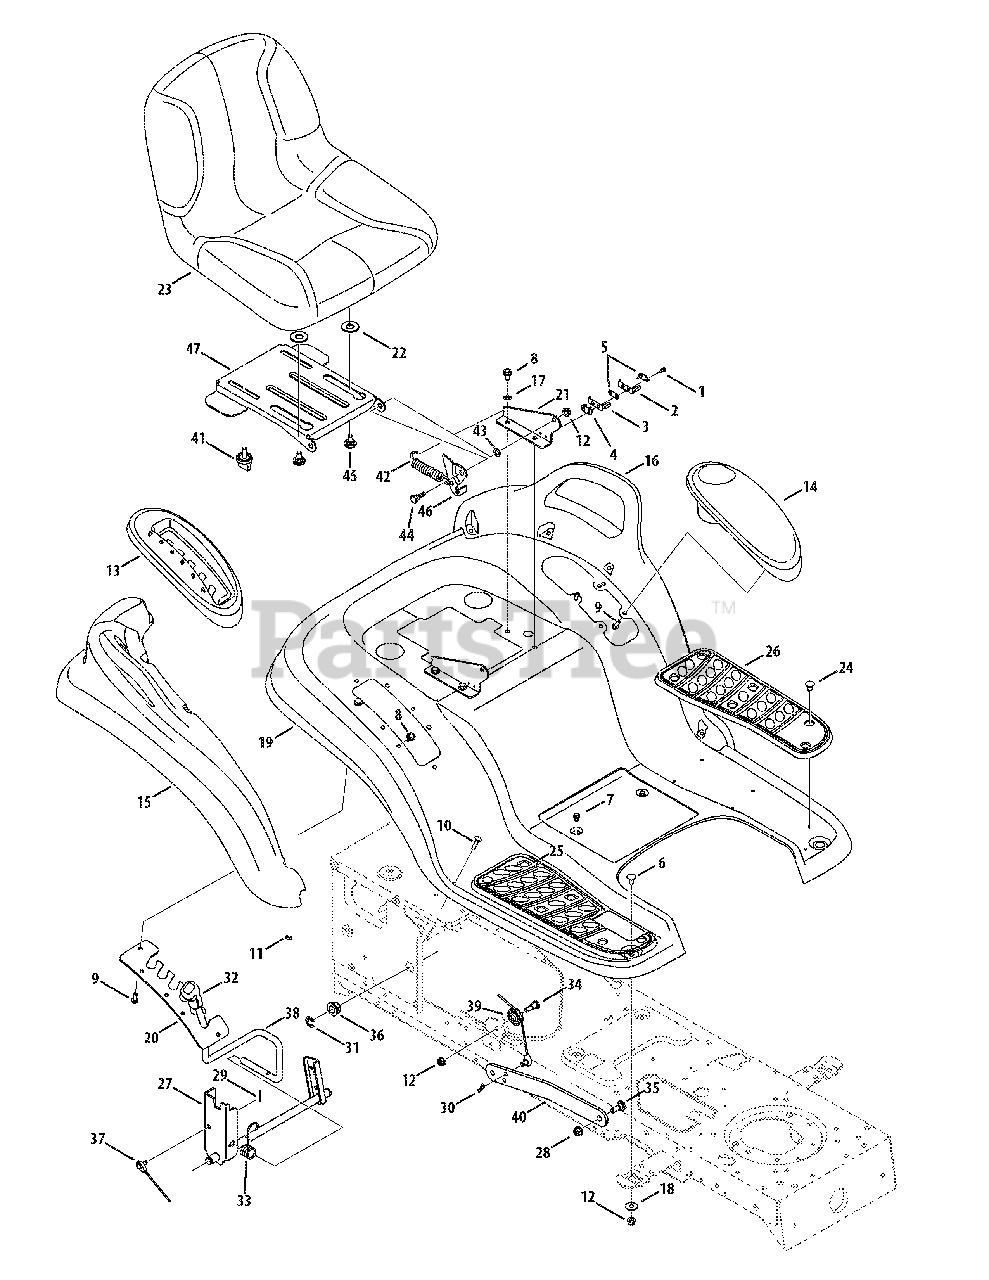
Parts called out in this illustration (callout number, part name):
1	Screw, #8-18 x.500
2	Outer Seat Spring Switch
3	Inner Seat Spring Switch
4	Insulator Boss Plate
5	Insulator Plate
6	Carriage Bolt, 5/16-18 x.750
7	Screw, 1/4-20 x.500
8	Screw, 5/16-18 x.750
9	Self-tapping Screw, 1/4-15 x.75
10	Carriage Screw 1/4-20 x 1.00
11	Sems Nut 1/4-20
12	Flange Lock Nut, 5/16-18
13	Lift Lever Cover
14	Cover w/ Cup Holder
15	RH Fender Flare
16	LH Fender Flare
17	Flat Washer, 5/16 Int. Tooth
18	Flat Washer,.349 x 1.0 x.063
22	Washer, Flat, .406 x .875 x .059
23	High Back Seat, Gray
24	Foot Pad Clips
29	Hairpin Clip
33	Torsion Spring
34	Hex Cap Screw, 5/16-18 x.62
35	Shoulder Screw, 3/8-16
36	Hex Flange Bearing
37	Lift Cable, 16.16
39	Roller Pulley
41	Knob, 3/8-16 x .875
42	Extension Spring,.84 x 4.6
44	Shoulder Screw,.437 x.286
45	Shoulder Screw, 3/8-16 .625 x .145
46	Seat Lift Bracket
